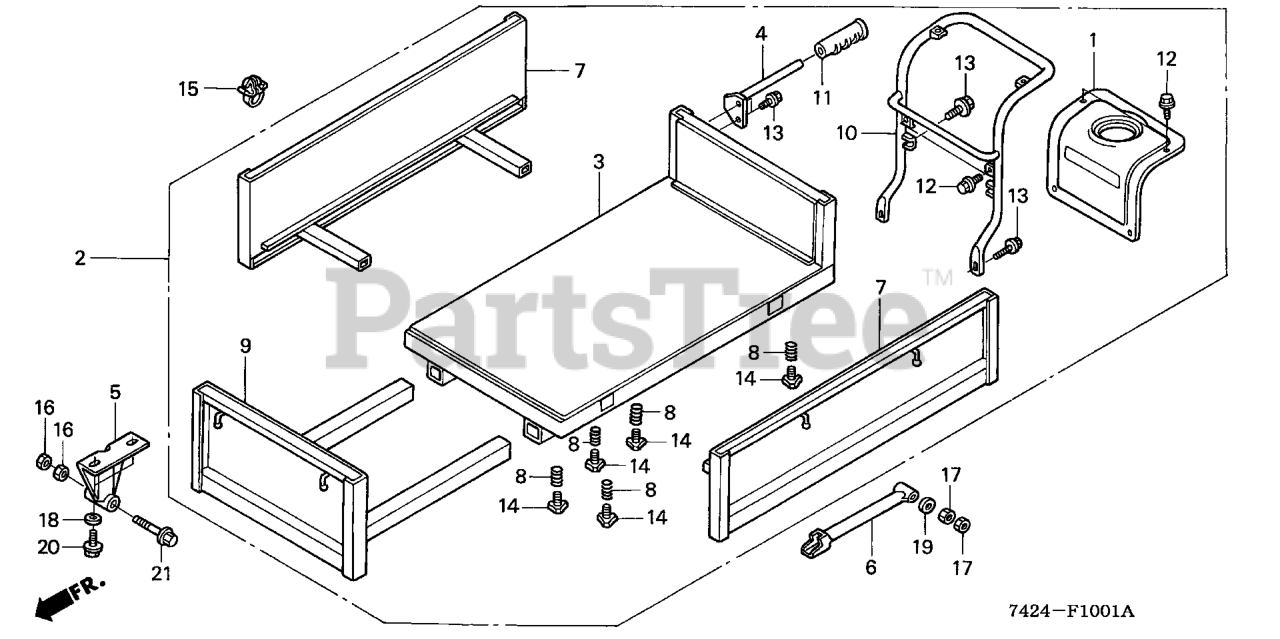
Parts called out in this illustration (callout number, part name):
1	PLATE, TANK GUARD *NH35M* (CLOUD SILVER METALLIC)
2	BODY ASSY., CARRIER *NH35M* (CLOUD SILVER METALLIC)
3	BODY, CARRIER
4	HANDLE, CARRIER
5	BRACKET, CARRIER
6	PIPE, DUMP LOCK
7	PIPE, GUIDE
8	SPRING, KNOB BOLT
9	PLATE, FR. STOPPER
10	PIPE, ENGINE GUARD
11	GRIP, HANDLE
12	BOLT, FLANGE (6X10)
13	BOLT, FLANGE (8X16)
14	BOLT, KNOB
15	CLIP, WIRE HARNESS (8MM) *NH1* (BLACK)
16	NUT, HEX. (12MM) Use up to Frame SN 5002482.
17	NUT, HEX. (12MM)
18	WASHER, PLAIN (8MM)
19	WASHER, PLAIN (12MM)
20	BOLT, FLANGE (8X20)
21	BOLT, FLANGE (12X80)
